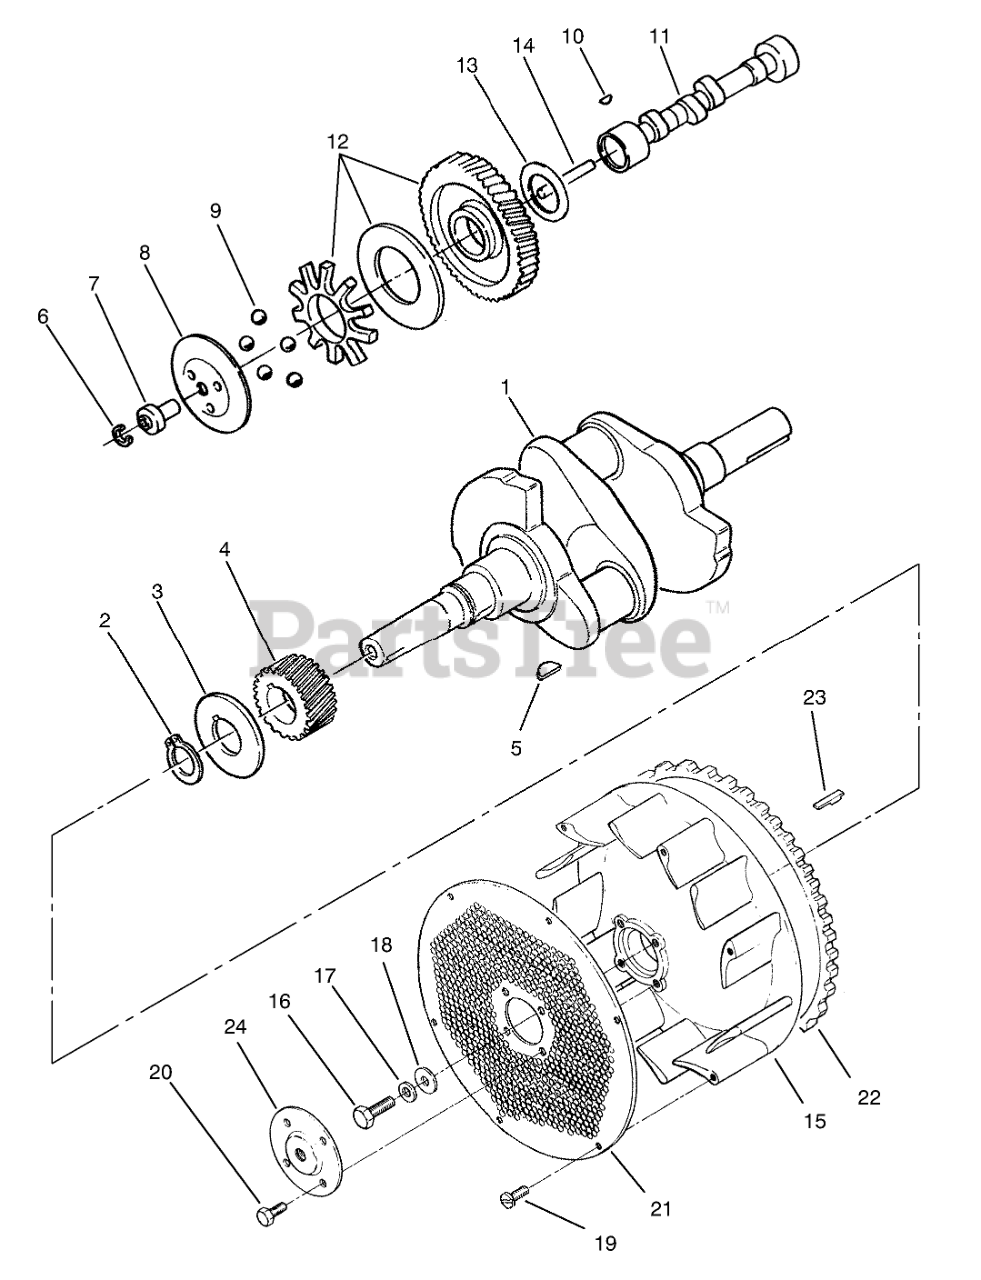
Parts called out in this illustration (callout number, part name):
1	CRANKSHAFT
3	WASHER
7	HUB-GOVERNOR CUP
8	CUP-GOVERNOR
9	BEARING
11	CAMSHAFT (16&18HP)
12	GEAR ASM
13	WASHER-THRUST
14	PIN-CENTER
15	Flywheel-w/Ring Gear
16	SCREW
17	Washer
18	WASHER-FLAT
19	Bolt
20	HX HD LOCK CAPSCREW
21	Screen
23	Key
24	LIFTING-BRKT (ZINC)
